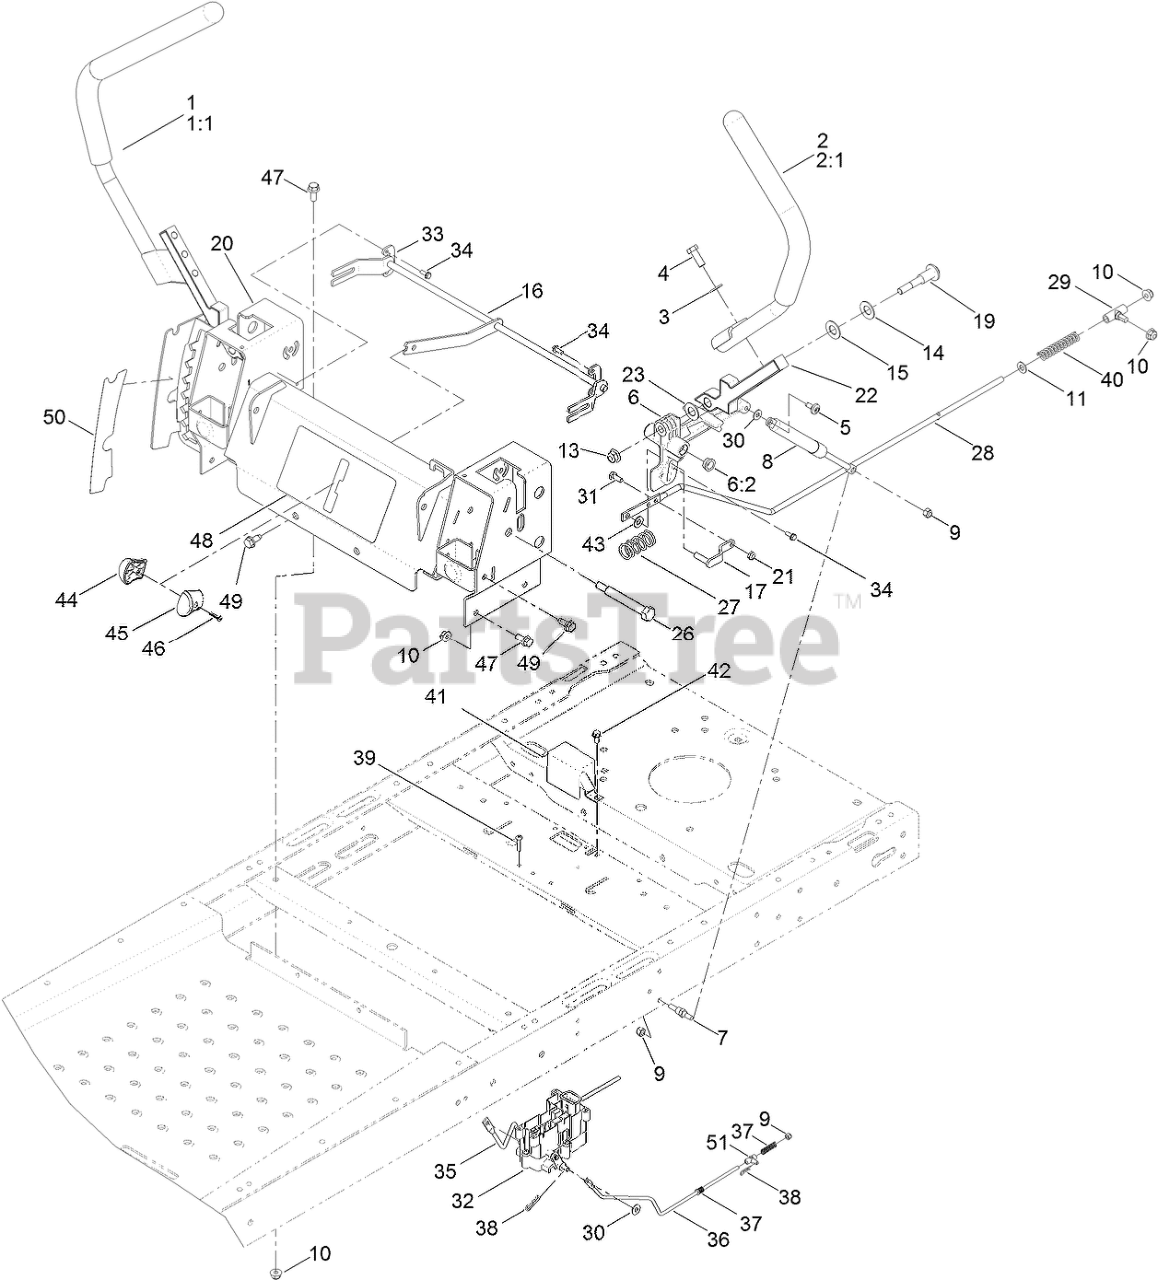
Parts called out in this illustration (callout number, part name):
1	HANDLE-CONTROL, RH
2	HANDLE-CONTROL, LH
3	WASHER-FLAT
4	SCREW-HH
5	SCREW-SHOULDER
6	ACTUATOR ARM ASM
6:2	BUSHING-FLANGE
7	STUD-DAMPER
8	Damper-Control, Motion
9	NUT-LOCK, NI
10	NUT-HF, NI
11	WASHER-PLAIN
13	NUT-HF, NI
14	WASHER-BELLEVILLE
15	WASHER
16	CONTROL-SPEED
17	PIN-ROD, HYDRO
19	BOLT-PIVOT
20	CONTROL BOX ASM
21	NUT-LOCK, NI
22	LEVER-CONTROL
23	WASHER-NYLON
26	BOLT-PIVOT
27	SPRING-RETURN
28	ROD-HYDRO
29	MOUNT-ROD, HYDRO
30	WASHER
31	SCREW-HH
32	BRAKE CONTROL MODULE ASM
33	RETAINER
34	SCREW-TAPTITE
35	ROD-BRAKE, RH
36	ROD-BRAKE, LH
37	SPRING-COMPRESSION
38	PIN-COTTER
39	SCREW-PPH
40	SPRING-RETURN, NEUTRAL
41	COVER-BRAKE
42	SCREW-HWH
43	SPACER-NYLON
44	KNOB-RH
45	KNOB-LH
46	SCREW-PPH
47	SCREW-HHF
48	DECAL-SPEED CONTROL
49	SCREW-HWHTF
50	DECAL-HOC
51	MOUNT-PIVOT
